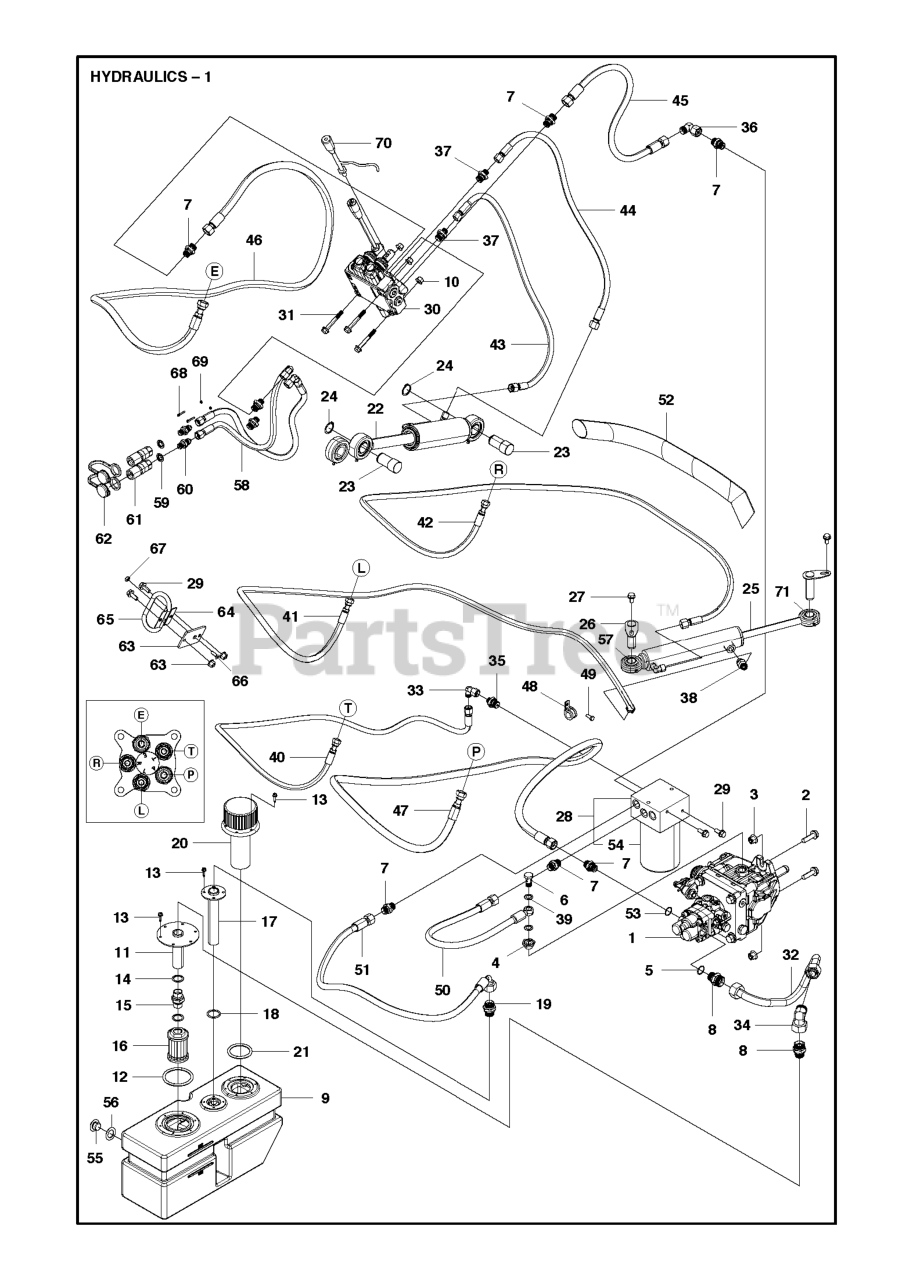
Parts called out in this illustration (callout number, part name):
10	NUT FLANGE
12	O-RING 61.2X5.7 NITRIL
15	PIPE FITTING G STRAIGHT 1/2-1/
16	FILTER PUMP SUCTION, AWD
18	O-RING 26.2X3.0 NITRILE
21	O-RING 47.2X5.7 NITRIL
24	RETAINING RING SGA 25
39	GASKET 20X14X1.5 COPPER
48	HOSE CLAMP
53	REPL BY 740 48 14-02
69	NUT M6M M3
